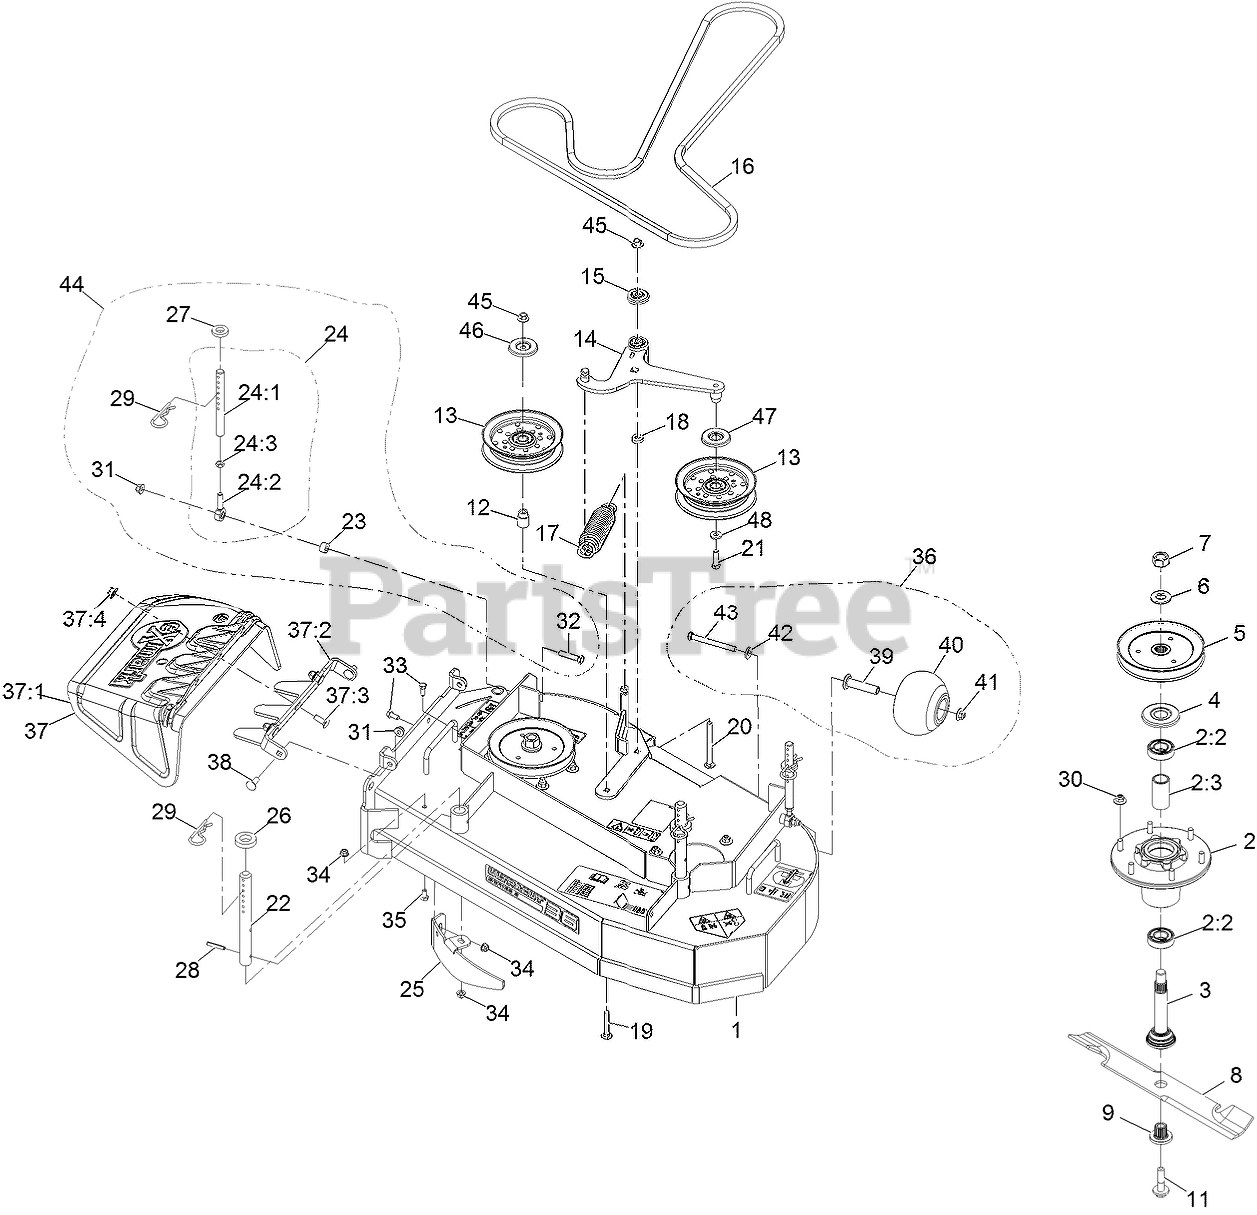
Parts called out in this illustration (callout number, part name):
1	ASM, DECK W/ DECALS, 36
2	ASM-CUTTER HSG WITH BEARINGS
2:2	BEARING-BALL
2:3	SPACER-BEARING
3	ASM-SPINDLE AND SEAL
4	GUARD,BEARING TOP .989
5	SHEAVE,BLADE DRIVE 6.50
7	NUT-HEX
9	BUSHING,SPLINED
11	SCREW,SEMS 1/2-20 X 2.19
12	BUSHING-IDLER
13	IDLER-PULLEY, FLAT
14	ASM-ARM, IDLER
15	GUARD-TOP
17	SPRING-EXTENSION
18	SPACER
19	Bolt-Carriage 3/8-16 X 2 1/4
20	SCREW-CARR
21	SCREW-HH
22	ROD, DECK SUPPORT TTS
24:1	LINK,SUPPORT
24:2	BALLJOINT
24:3	NUT-HJ
25	BAFFLE, DOGLEG
26	SPACER-DECK SUPPORT
29	PIN,HAIR COTTER
30	Nut-Nyloc 3/8-16 Flg
31	NUT-HF, NI
32	SCREW-HH
33	SCREW-HH
34	NUT-HF, NI
35	SCREW-HH
36	KIT, ANTI-SCALP ROLLER
37	ASM, DISCHARGE CHUTE
37:1	CHUTE,DISCHARGE
37:2	BRACKET, DISCHARGE CHUTE
37:3	SCREW-CARR
37:4	Nut-Nyloc 3/8-16 Flg
38	SCREW-CARR
39	AXLE, ROLLER
40	ROLLER-SCALP, ANTI
41	Nut-Nyloc 3/8-16 Flg
42	WASHER-BELLEVILLE
43	SCREW-HH 3/8-16 X 3 3/4 GR 8
44	KIT,SUPPORT LINK W/PIN
46	SHIELD-DUST
47	SHIELD-GUARD, DUST
